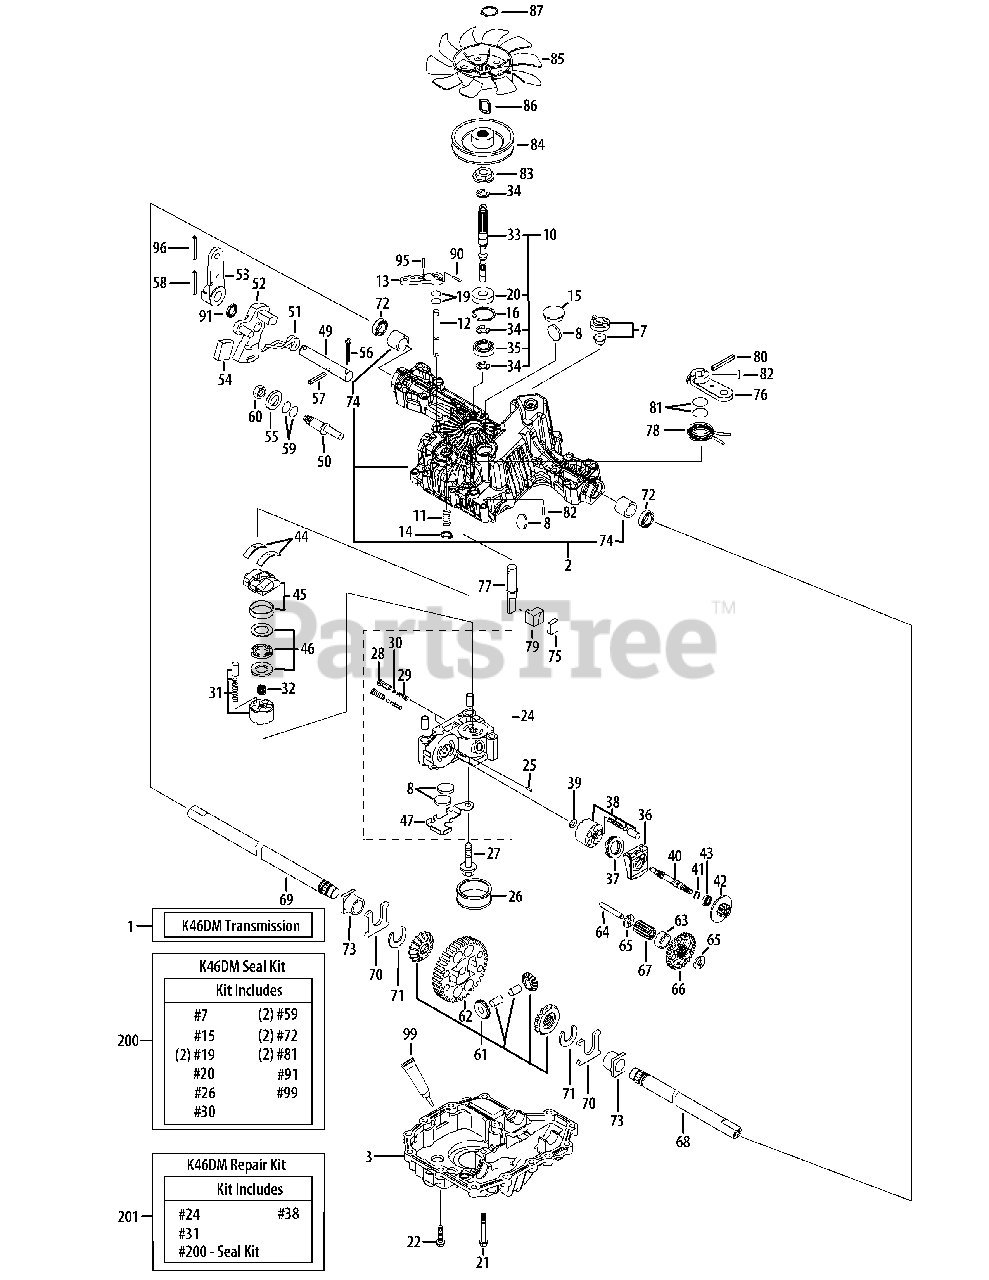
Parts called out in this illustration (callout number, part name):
1	K46DM Transaxle
10	Pump Shaft/Bearing Kit
12	Bypass Shaft A
15	Sealing Cap 30
16	Snap Ring C 35
19	O-Ring 1A P10A
20	Seal TC 153507
21	Tapping Screw 8 x 55
22	Tapping Screw 8 x 30
24	Kit, Center Case
26	Filter 105
28	IDS Valve 1.2
30	IDS Filter 300
31	Kit, Cylinder Block (Pump)
35	Bearing 6202
36	Motor Housing
37	Thrust Bearing 51106
38	Kit, Cylinder Block
39	Washer 12 x 24 x 1
41	Snap Ring S15
42	Brake Disc/Motor Gear
44	Thrust, Plastic
45	Swash Plate Clamp
46	Kit, Thrust Bearing (Pump)
47	Magnet Holder
49	Control Shaft
51	Torsion Spring, Standard
52	Control Lever
53	Control Lever F
56	Cotter Pin 1/8" x 3/4"
57	Spring Pin 6 x 36
58	Roll Pin 6 x 40
61	Diff Gear Kit
62	Final Gear (54T)
63	Final Pinion Collar
64	Reduction Shaft
65	Washer 12 x 32 x 3.2
66	Reduction Gear (37T)
67	Final Pinion Gear (10T)
68	Axle Shaft, Left
69	Axle Shaft, Right
70	Thrust Washer
72	Seal 19 x 32 x 8
73	Bushing 19 x 25
74	Bushing 19.05
78	Brake Return Spring
79	Brake Actuator
80	Spring Pin 5 x 32
81	O-Ring 1A P12
82	Spring Pin 4 x 16
83	Spline Collar
90	Spring Pin 3.0A x 20
91	Oil Seal 16 x 22 x .03
95	Spring Pin 3.0A x 16
96	Roll Pin 3.5 x 40
99	Sealant
200	Kit,Seal Incl. 7, 15, 19, 20, 26, 30,59, 72, 81, 91 & 99
201	Repair Kit, Incl. 24, 31, 38 & 200
